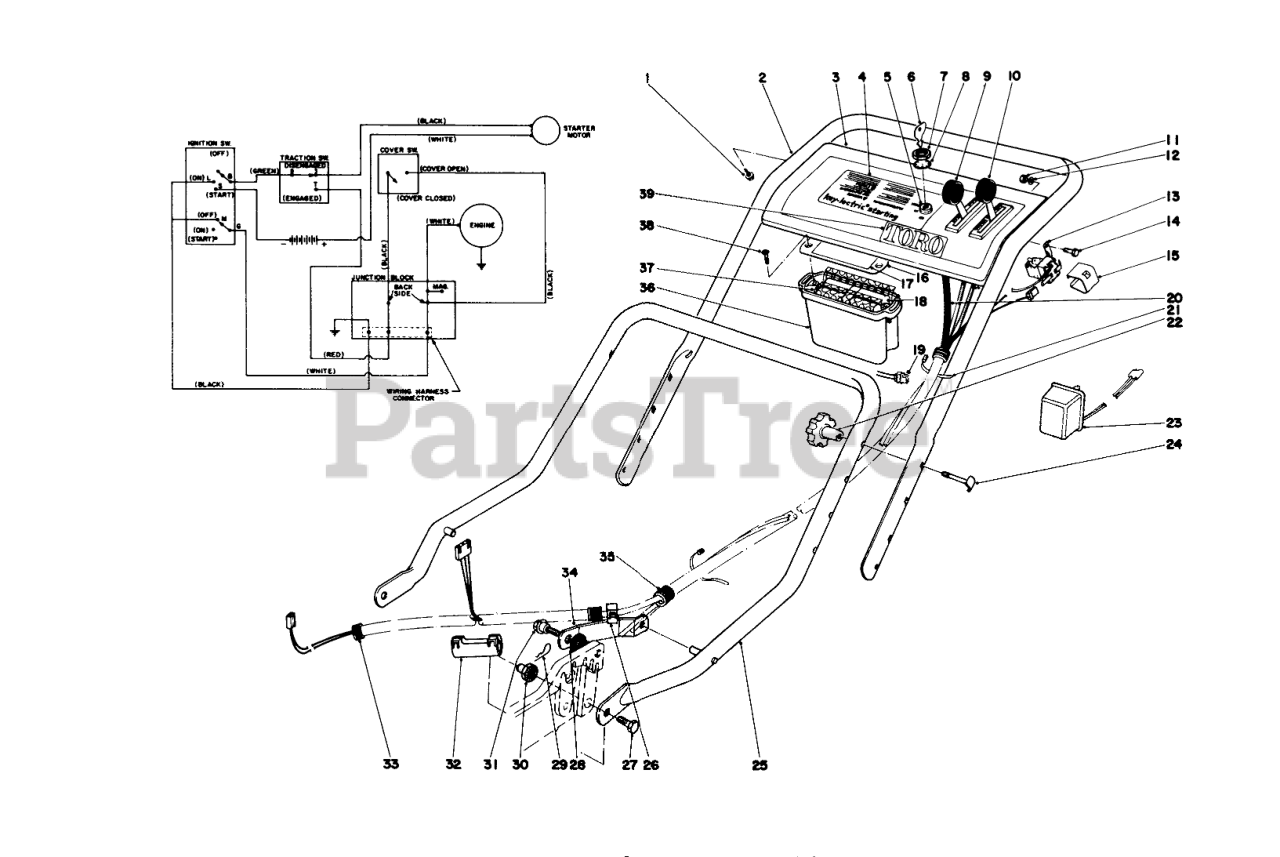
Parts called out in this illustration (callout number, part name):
1	SCREW-HWHTF
2	Upper Handle
3	Control Plate
4	Decal Control Plate
5	SWITCH-STARTER
6	Key
7	NUT-HH
8	WASHER-TOOTH, INTERNAL
9	Throttle Control
10	Control-Traction
11	NUT-HEX
12	WASHER-FLAT
13	CONTROL SWITCH
14	SCREW-HH
15	Cover Switch
16	Cover
17	Decal Battery
18	Battery Pack Assembly (Incl. Ref. #16-19 & 36-38)
19	Plug & Wire
20	Wiring Harness
21	TIE-CABLE
23	Charger
24	HANDLE SCREW
25	Lower Handle
26	RING FITTING
27	SCREW-HH
28	SPACER
29	PIN-COTTER, HAIR
30	HANDLE PIVOT NUT
31	SCREW-SHOULDER
32	Breakout Fitting
33	WIRING HARNESS COVER
34	HANDLE LATCH
35	Upper Wiring Harness
36	Container Pack
37	Spacer
39	TORO LOGO DECAL
